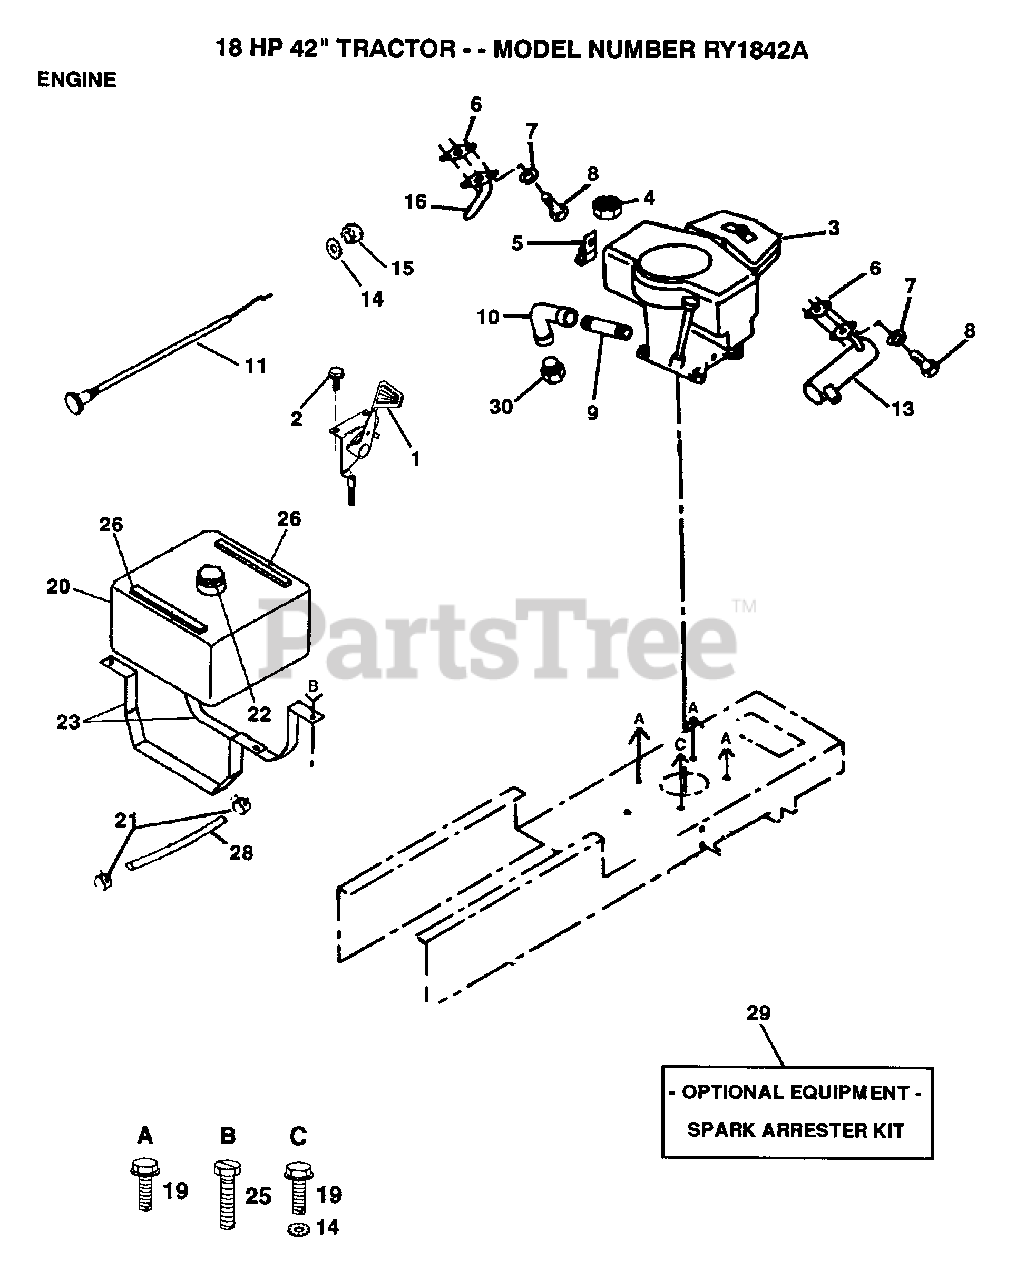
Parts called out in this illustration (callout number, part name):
2	SCREW LT
4	NUT
5	CLIP T
7	LOCKWASHER
9	PIPE NIPPLE LT
10	ELBOW
11	CHOKE CONTROL
14	LOCKWASHER
16	EXHAUST TUBE T
19	SCREW
21	HOSE CLAMP
23	"STRAP,TANK"
25	SCREW LT
26	"STRIP,FORM"
28	FUEL LINE T
